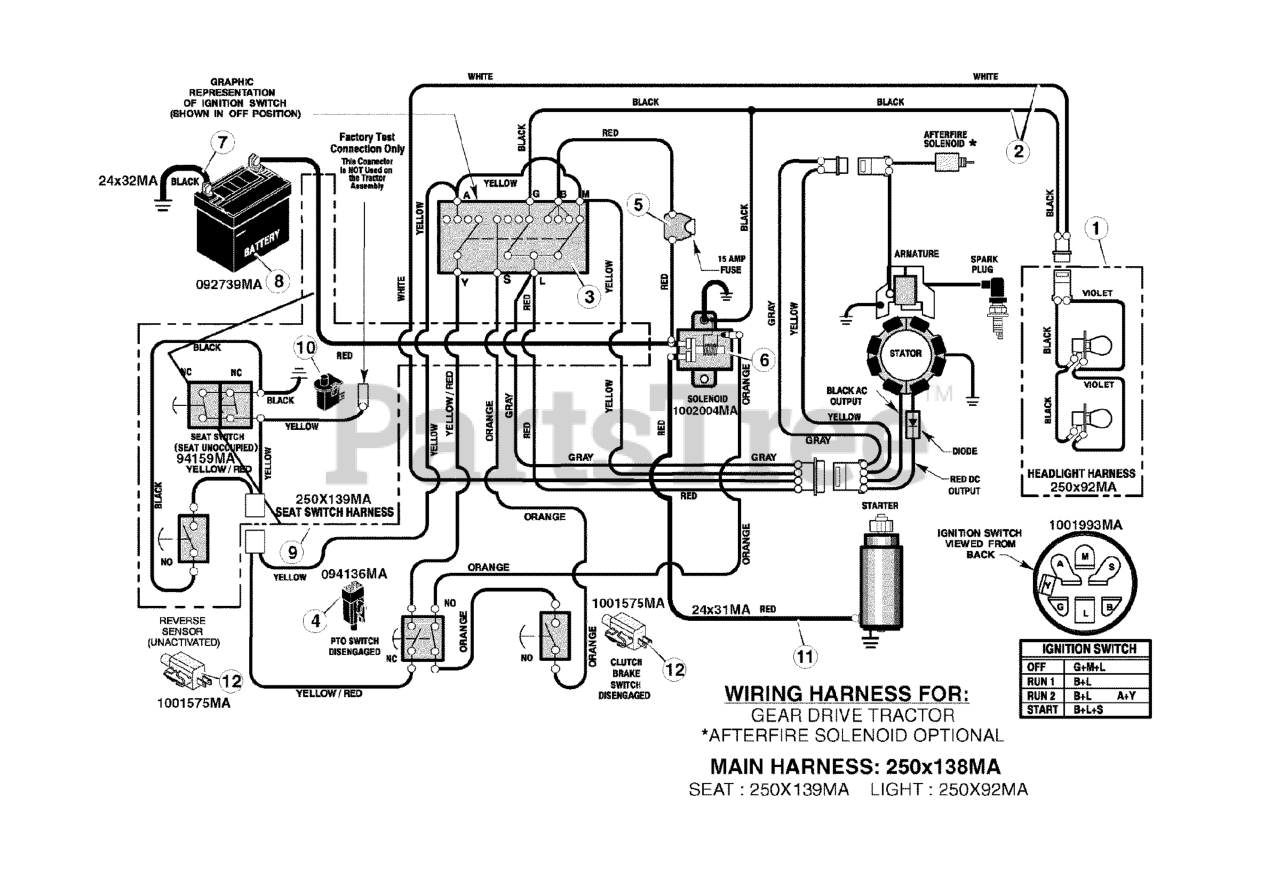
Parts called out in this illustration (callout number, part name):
1	Harness, Light Wire
2	Harness, Chassis Wire
3	Switch, Ignition
4	Switch, Limit
6	Solenoid
7	Cable, Battery Ground
8	Battery
9	Harness, Seat Switch Wire
10	Switch, Seat Sensor
12	Switch, Limit
